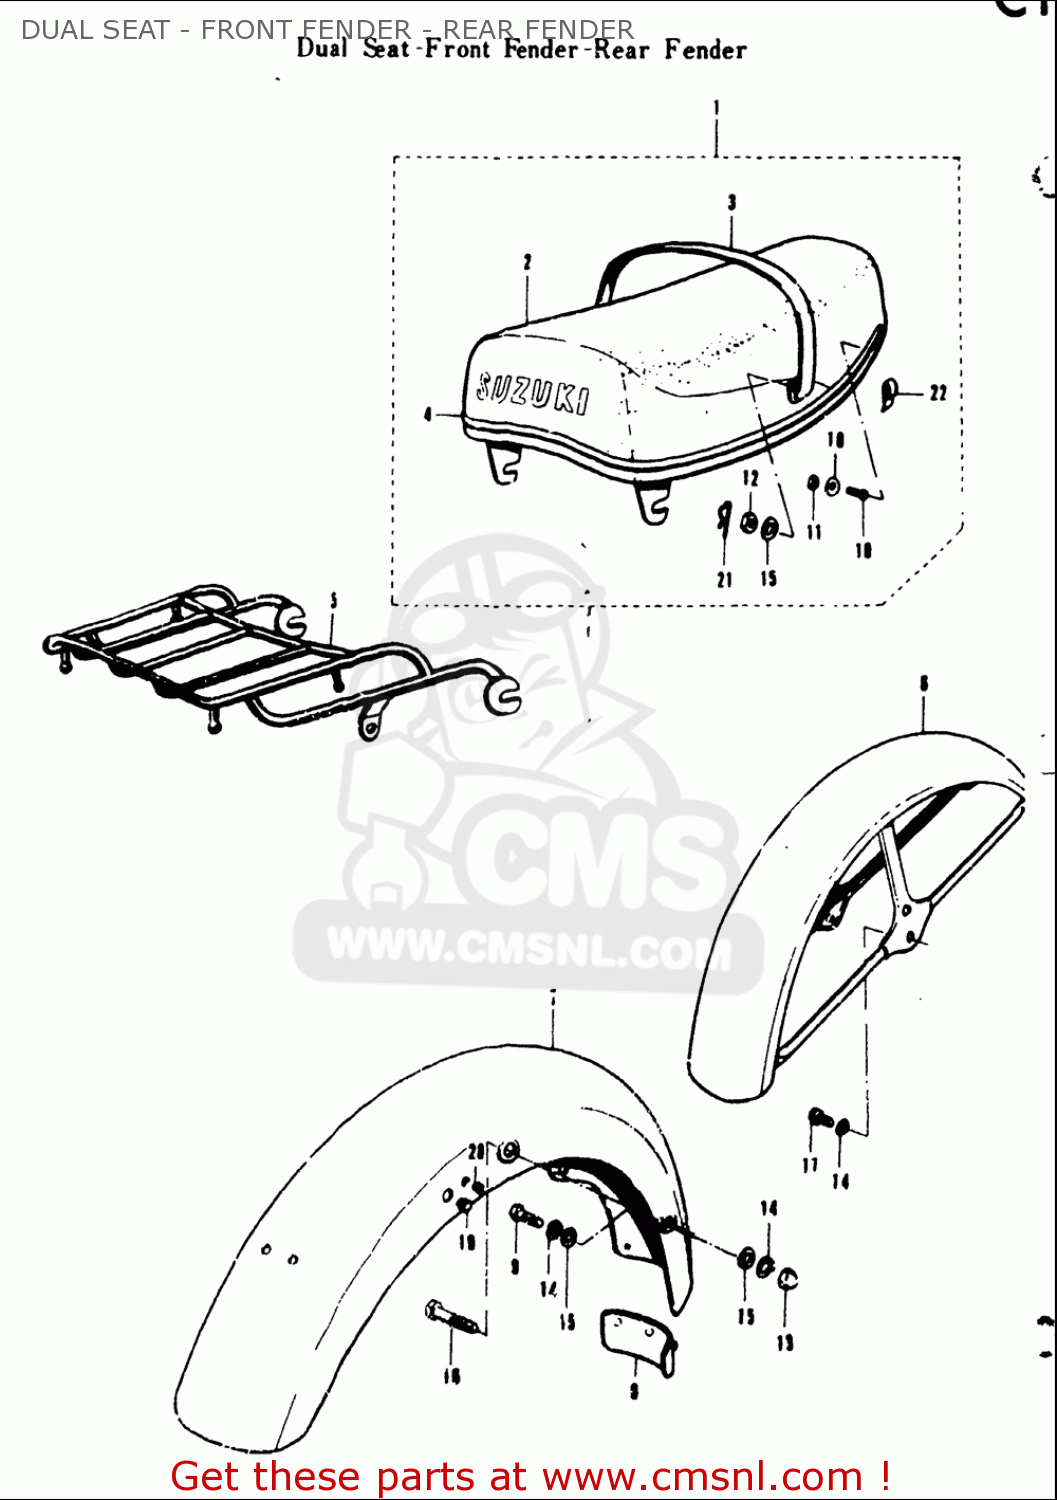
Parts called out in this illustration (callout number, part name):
11	NUT
12	NUT
13	NUT
14	WASHER,LOCK
15	WASHER
16	BOLT(8X47)
17	BOLT
21	CLIP
